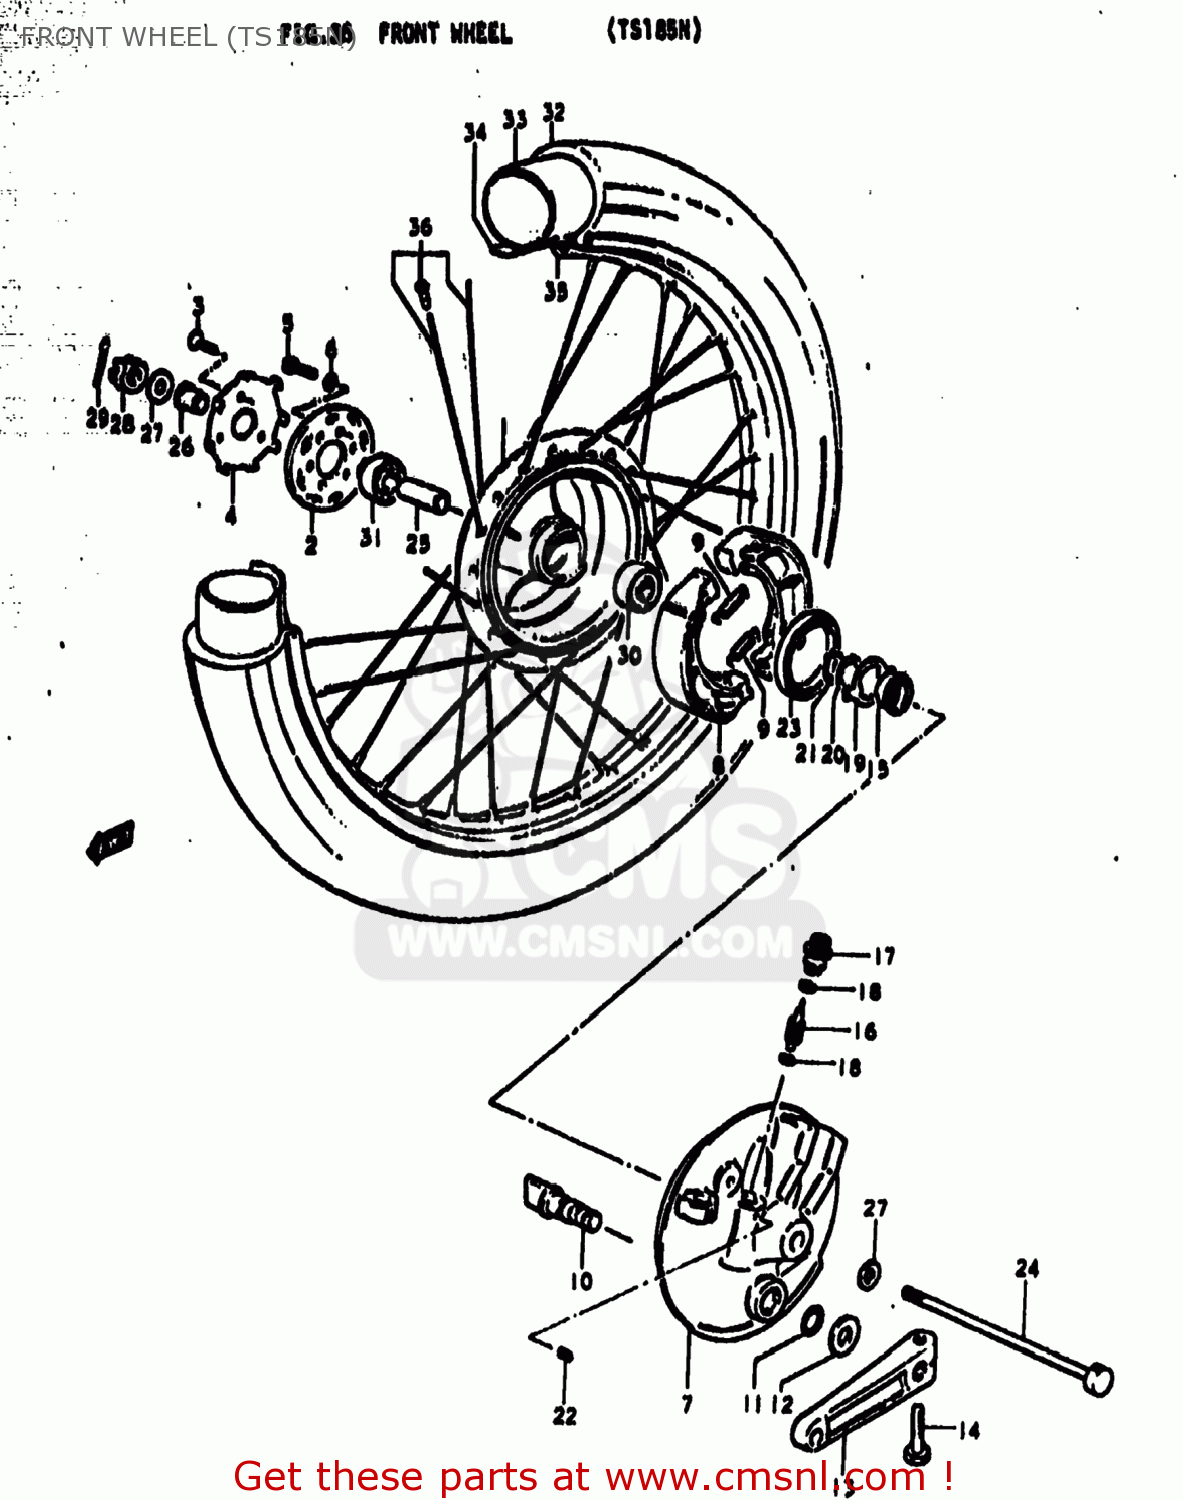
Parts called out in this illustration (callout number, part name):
1	HUB,FR WHEEL
2	FLANGE,FR HUB,R
3	SCREW
4	RETAINER,FR HUB BEARING,R
5	BOLT, UPPER
6	LOCK WASHER
7	PANEL,FRONT HUB
8	SHOE,BRAKE
9	SPRING(L:34)
10	CAM,FRONT BRAKE
11	O RING(D:2.5,ID:11.4)
12	WASHER(12.5X20X1)
13	LEVER,FRONT BRAKE CAM
14	BOLT
15	GEAR,SPEEDOMETER
16	PINION,SPEEDOMETER
17	BUSH,METER GEAR OUTER
18	WASHER (5.1X9X0.4)
19	DRIVER,SPEEDOMETER GEAR
20	WASHER(18.5X24X1)
21	CIRCLIP
22	SCREW
23	OIL SEAL (43X58X7)
24	AXLE,FRONT
25	SPACER (12.6X19X52)
26	SPACER,FR AXLE,R
27	WASHER
28	NUT 12MM
29	COTTER PIN
30	BEARING
31	BEARING, RH
32	TIRE,FRONT
33	TUBE
34	PROTECTOR,WHEEL,INNER
35	RIM,FR WHEEL(1.60X21)
36	SPOKE SET,FRONT
